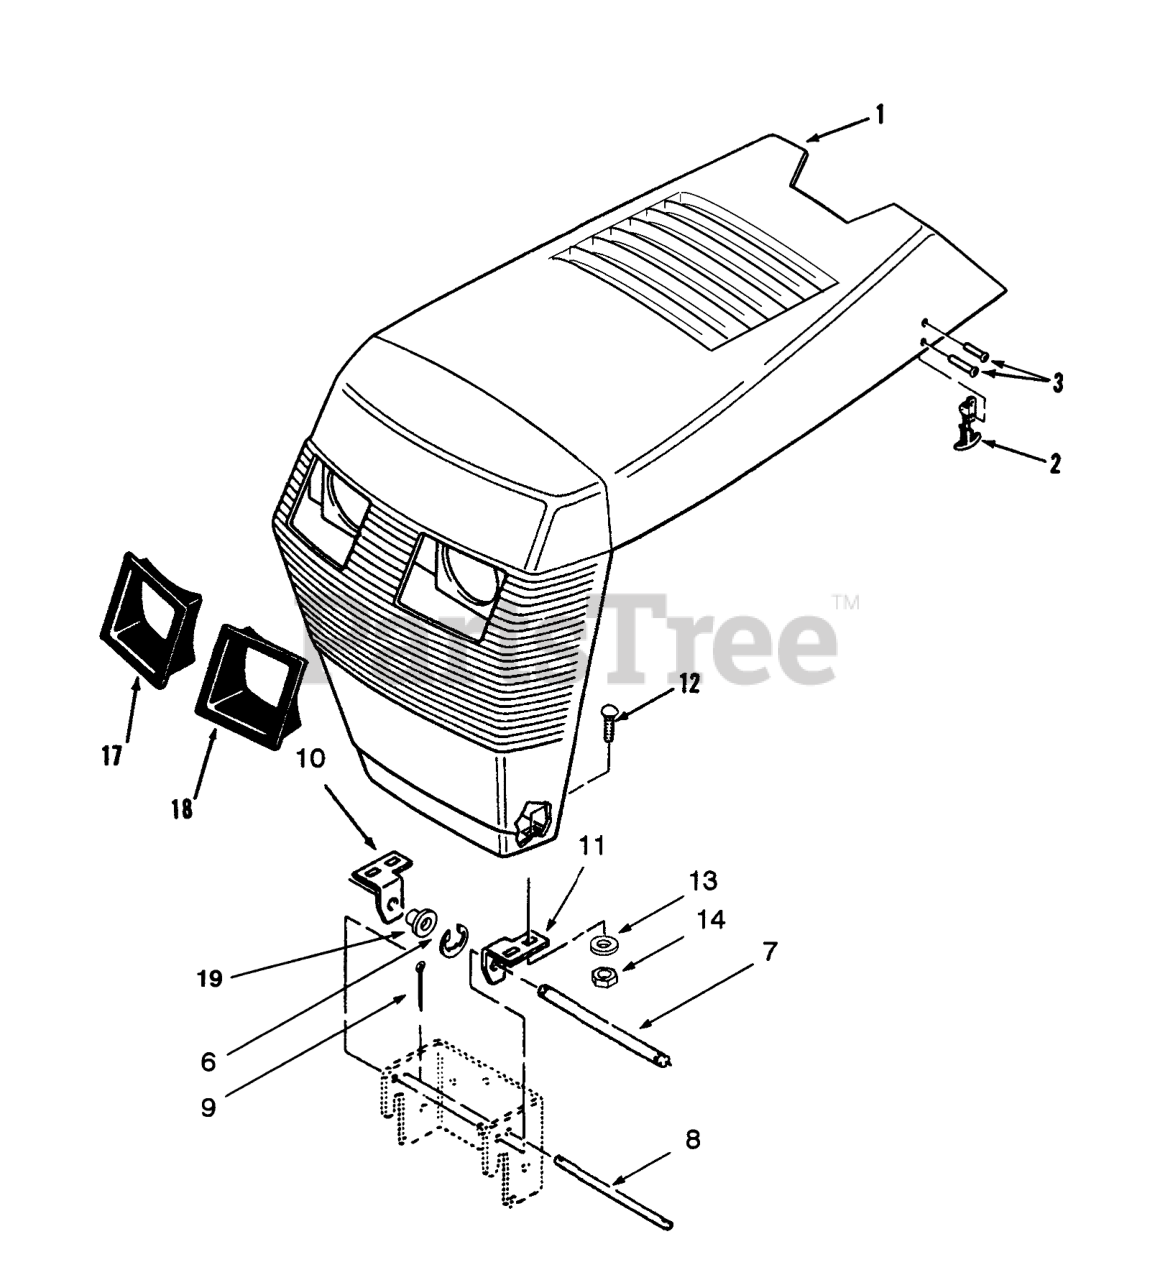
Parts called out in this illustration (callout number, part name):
1	SERV.ASSY-HOOD & PKG
2	LATCH-FLEX BLK ASS'Y
3	RIVET-POP
6	RING-RETAINING
7	ROD-GRILL PIVOT
8	ROD-HOOD STOP
9	Pin-Cotter
10	BRACKET-GRILL, R H
11	BRACKET-GRILL, LH
12	SCREW-CARR
13	WASHER-FLAT
14	NUT-LOCK, NI
17	BEZEL-HEADLIGHT, RH
18	BEZEL-HEADLIGHT, LH
19	BUSHING-NYLINER
